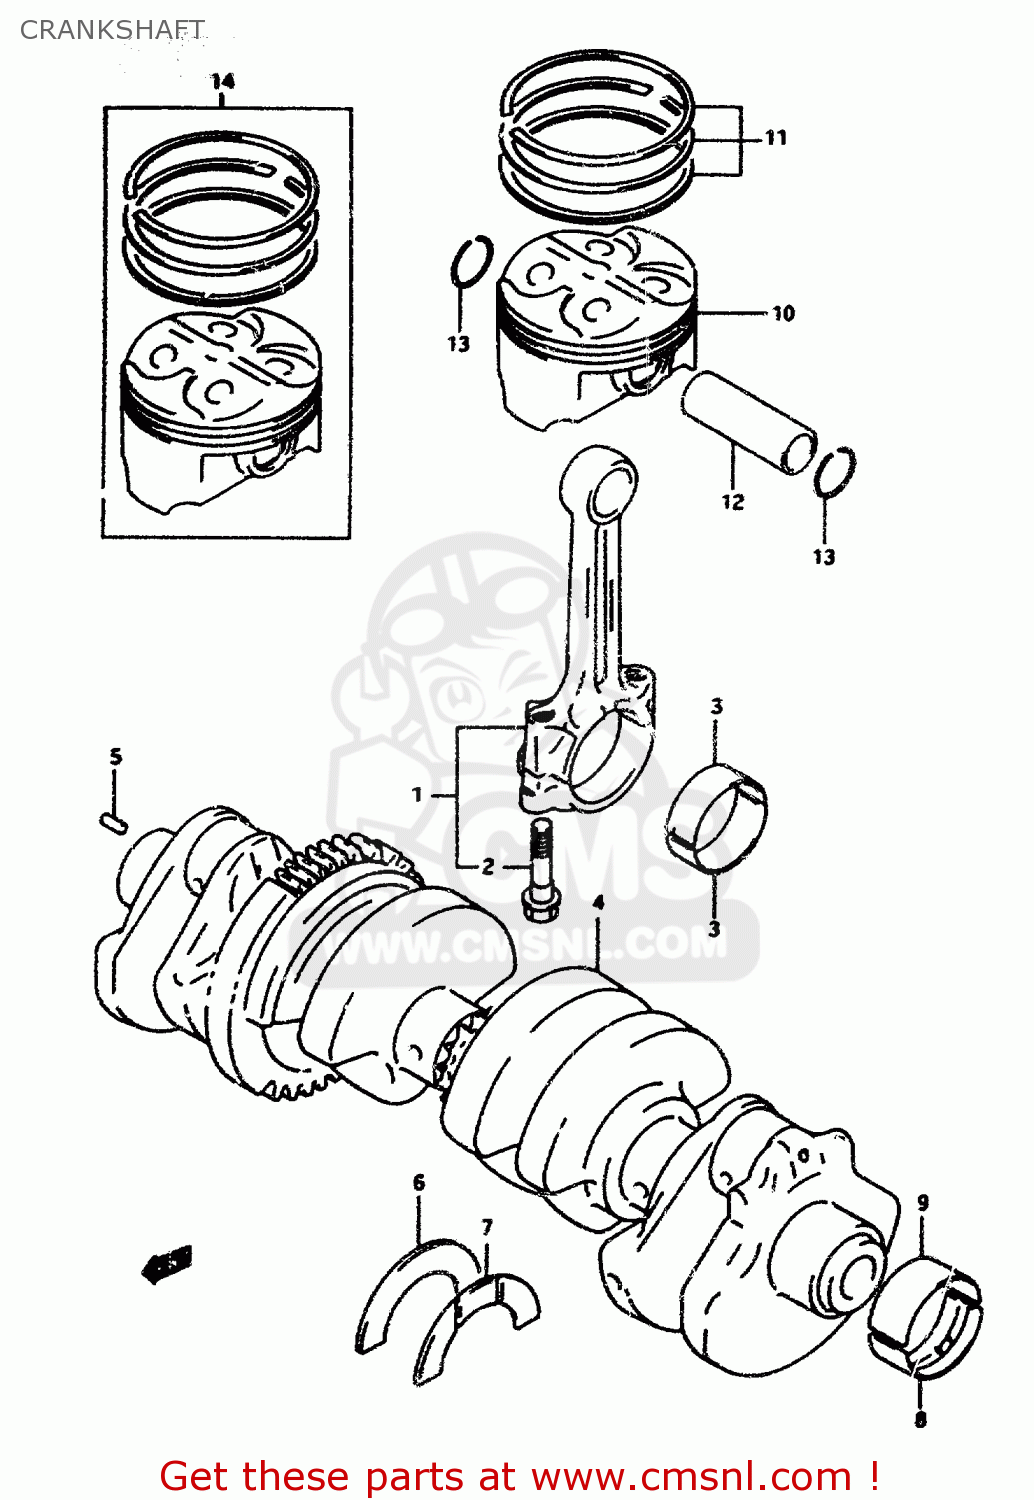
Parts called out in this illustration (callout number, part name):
1	CONNECTING ROD ASSY
2	BOLT,CONNECTING ROD
3	BEARING,CRANK PIN
4	CRANKSHAFT SET
5	PIN
6	BEARING,CRANK THRUST(GREEN)
7	BEARING,CRANK THRUST(RED)
8	BEARING,CRANKSHAFT(GREEN)
9	BEARING,CRANKSHAFT(GREEN)
10	PISTON
11	RING SET,PISTON
12	PIN,PISTON
13	RING,SNAP 16MM
14	PISTON SET (OS:0.5)
